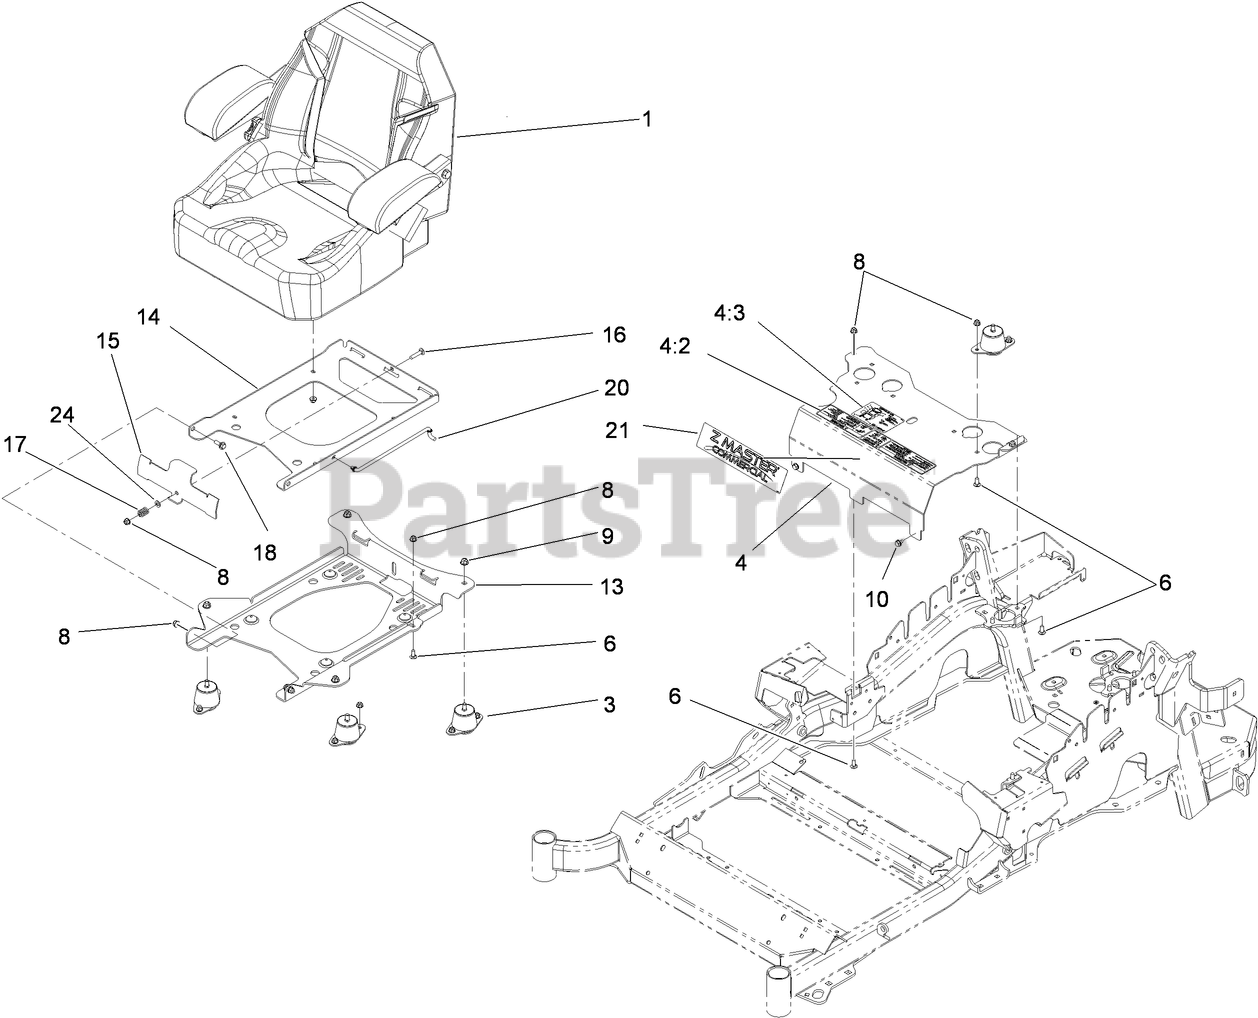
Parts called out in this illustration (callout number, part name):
1	SEAT-STANDARD
3	ISOLATOR-SEAT
4	MOUNT-SEAT
4:2	DECAL-CONSOLE
4:3	DECAL-SERVICE AID
6	SCREW-CARR
8	NUT-HF, NI
9	NUT-HF, NI
10	SCREW
13	PLATE-SUPPORT, SEAT TILT
14	PLATE-FRAME, SEAT TILT
15	PLATE-LATCH, SEAT
16	BOLT-CARR
17	SPRING-COMPRESSION
18	SCREW-SHOULDER
20	ROD-PROP
24	WASHER-PLAIN
